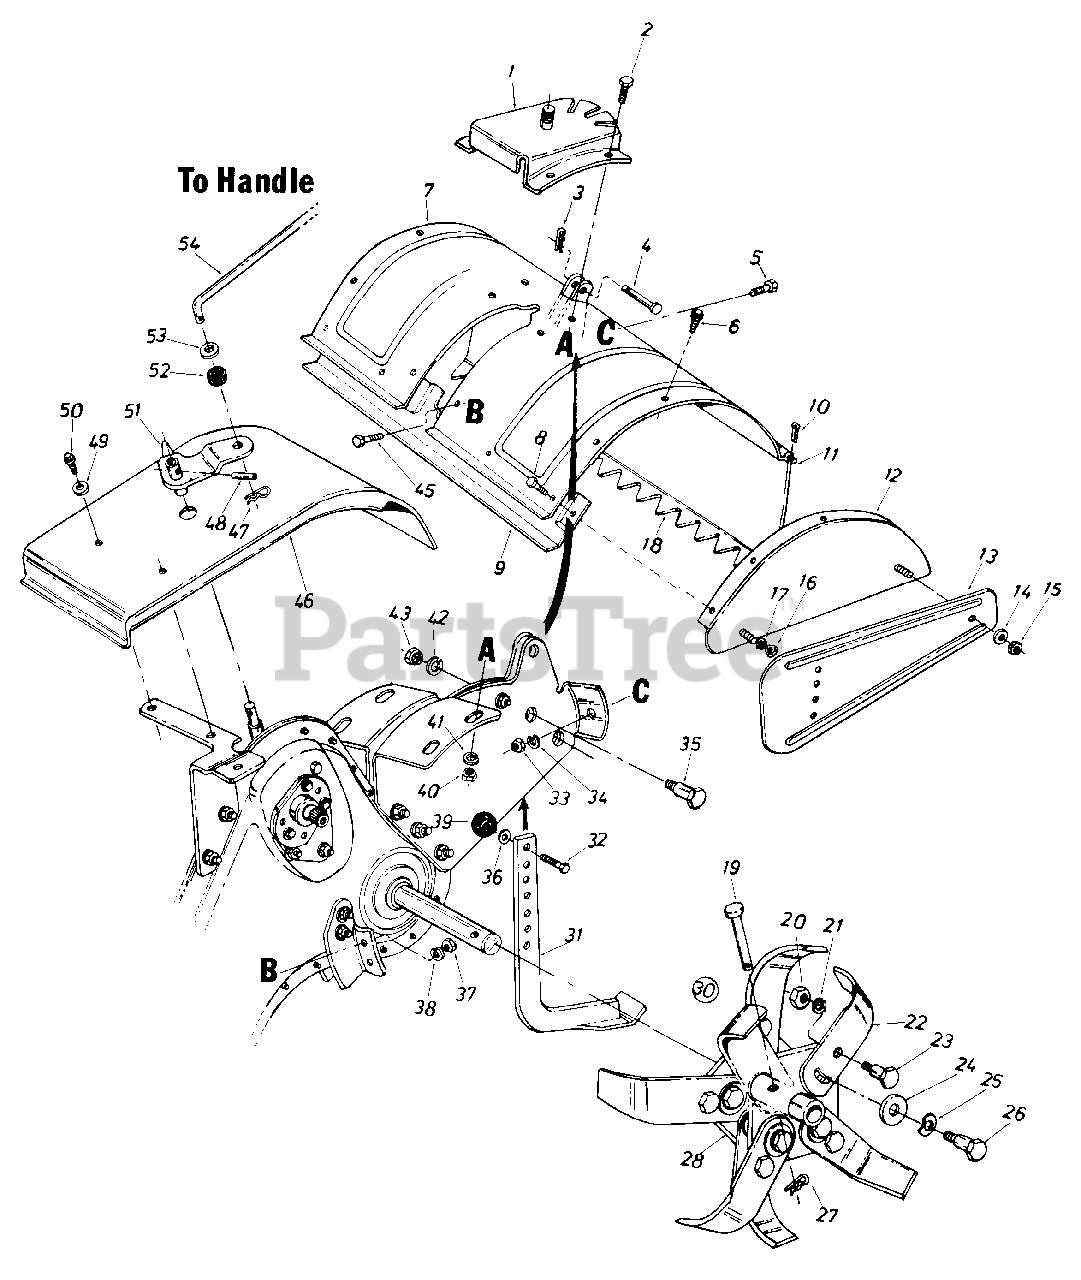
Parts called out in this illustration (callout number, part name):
1	Handle Positioner Brkt. Ass'y.
2	Hex Bolt 3/8-16 x .75" Lg.
3	Intern. Cotter Pin 5/16" Dia.
4	Clevis Pin .375" Dia.
5	Hex Bolt 5/16-18 x .75" Lg.
6	Hex Wash. Tap Scr.
9	Bracket Reinforcement 18"
10	Cotter Pin 3132" Dia. x .75" Lg.
11	Tiller Flap Rod
15	Hex Nut 5/16-18 Thd.
16	Hex Nut 5/16-18 Thd.
17	L-Wash. 5/16" I.D.
19	Clevis Pin .375" Dia.
20	Hex Nut 3/8-24 Thd.
21	L-Wash. 3/8" I.D. H.D.
23	Shld. Bolt 1/2" Dia. x .175
24	Fl-Wash. .51" I.D. x 1.50" O.D.
25	Bell-Wash. .515" I.D. x 1.14" O.D.
26	Shld. Bolt 1/2' Dia. x .320
27	Intern. Cotter Pin
32	Hex Bolt 3/8-16 x .75" Lg.
33	Hex Nut 5/16-18 Thd.
34	L-Wash. 5/16" I.D.
35	Shld. Bolt 1/2" I.D. x .62" Lg.
36	Fl-Wash. 3/8" I.D. x 5/8" O.D.
37	Hex Nut 5/16-18 Thd.
38	L-Wash. 5/16" I.D.
39	Ball Knob
40	Hex Nut 3/8-16 Thd.
41	L-Wash. 3/8" I.D.
42	L-Wash. 3/8" I.D.
43	Hex Nut 3/8-16 Thd.
45	Hex Bolt 5/16-18 x .75" Lg.
46	Shift Cover
47	Intern. Cotter Pin 5/16" Dia.
48	Spring Roll Pin 3/16" Dia. x 1.00" Lg.
49	Fl-Wash. .281" I.D. x .62" O.D.
50	Hex Wash. Self-Tap Scr. 1/4-20 x .50" Lg.
51	Shifting Crank Ass'y. D x 2.05
52	Rubber Washer .33" I.D. x .87" O.D.
53	Fl-Wash. .400" I.D. x 1.250" O.D.
54	Control Rod .33" Dia. x 37" Lg.
